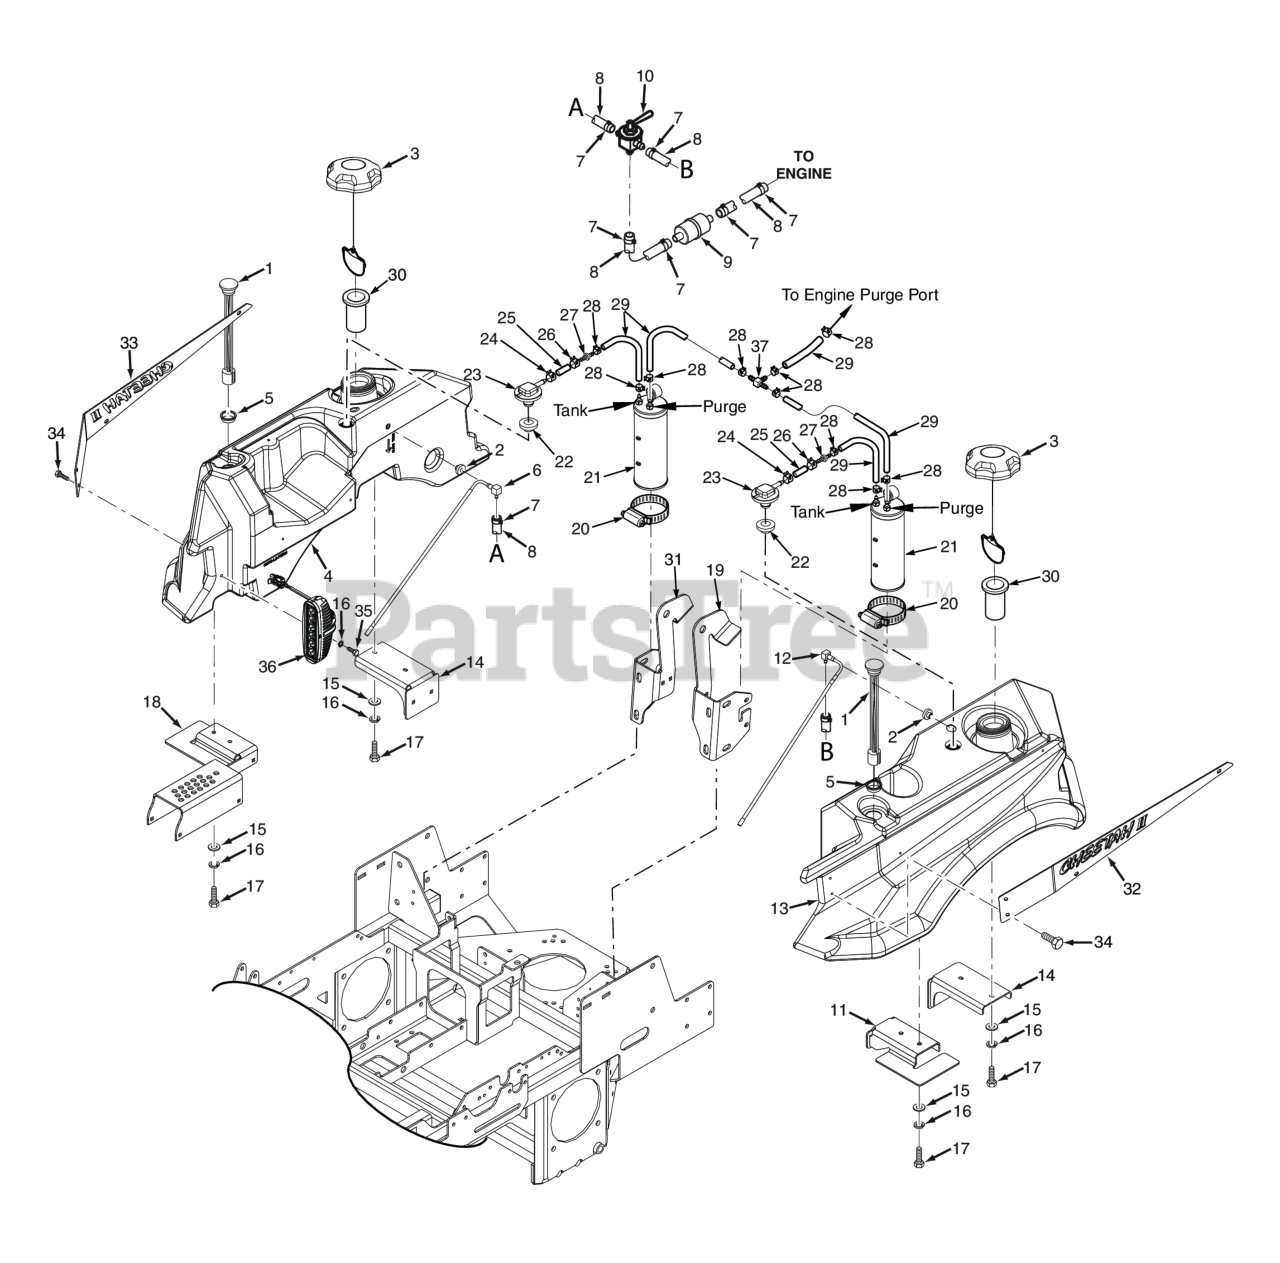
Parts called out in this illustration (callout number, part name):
1	Fuel Gauge Assembly
2	Bushing, 0.56" Dia. Viton
3	Fuel Cap w/ Tether (E.P.A.)
4	Fuel Tank Assembly, RH
5	Grommet, Fuel Gauge
6	Fuel Tube Assembly
7	Clamp, Fuel Hose 1/4" Hose I.D.
8	Fuel Hose, 1/4" I.D. Non-Perm (791DFI Fuel Return) - Order by Inch
9	Fuel Filter
10	Valve, Fuel Shut-Off
11	Mounting Bracket, Fuel Tank Front
12	Fuel Tube Assembly, LH
13	Fuel Tank Assembly, LH
14	Mounting Bracket, Fuel Tank Rear
15	Flatwasher, 5/16-.375 x .875 x .083 (35BV & 37BV-EFI)
16	Lockwasher, 5/16 (.317 x .586 x .078) Helical Spring
17	BOLT, SERRATED FLANGE HEX HEAD 5/16-18 X 3/4"
18	Adjustment Bracket, Upper Cut Height
19	ROPS Mount, LH, 29CV-EFI
20	Clamp, 3-1/2" Max. Dia.
21	Carbon Canister - SVR-52V / SVR-61V
22	Grommet, Viton,
23	Remote Vent, No Valve
24	CLAMP, FUEL HOSE(KAWASAKI ONLY)
25	Hose, 1/4" Vapor Recovery (order by inch)
26	CLAMP, FUEL HOSE(KAWASAKI ONLY)
27	Mender, 1/4 x 3/16 w/0.02 Hole
28	Clamp, Vapor Recovery Hose 3/16"
29	Hose, Vapor Recovery 3/16" (order by inch)
30	Tube, Fuel Tank Insert - 4"
31	ROPS Mount, RH, 29CV-EFI
32	Plate, LH Fuel Tank
33	Plate, RH Fuel Tank
34	CAP SCREW, 1/4-20 X 1/2" SERRATED FLANGE HEX
35	SOC HD CAPSCR, 5/16-18 X .75
36	Light Assembly
37	Tee, 3/16 x 3/16 x 3/16 Union, Hose Barb
